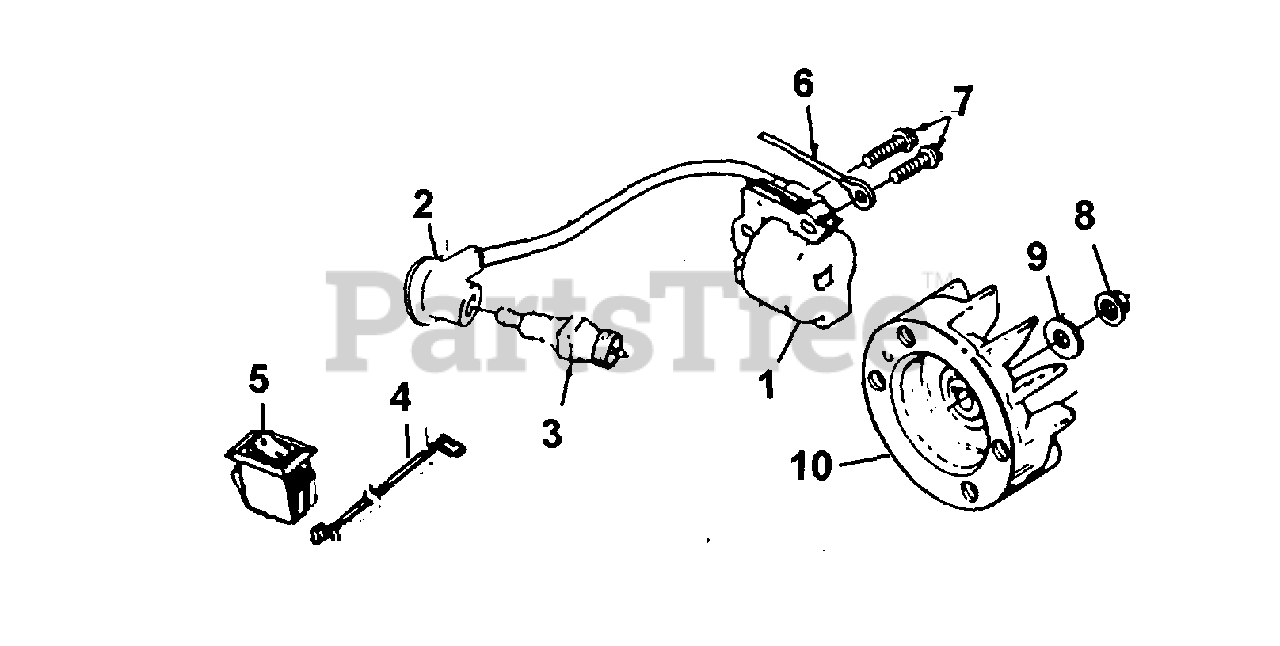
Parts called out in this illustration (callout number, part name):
1	MODULE, IGNITION
2	TERMINAL
3	SPARK PLUG
4	LEAD, DOUBLE FLAG
5	SWITCH, ROCKER
6	LEAD, RING TERMINAL
7	SCREW, TAPTITE (8-32 x 1")
8	NUT, (5/16 x 24)
9	WASHER, THRUST
10	ROTOR ASSY.
